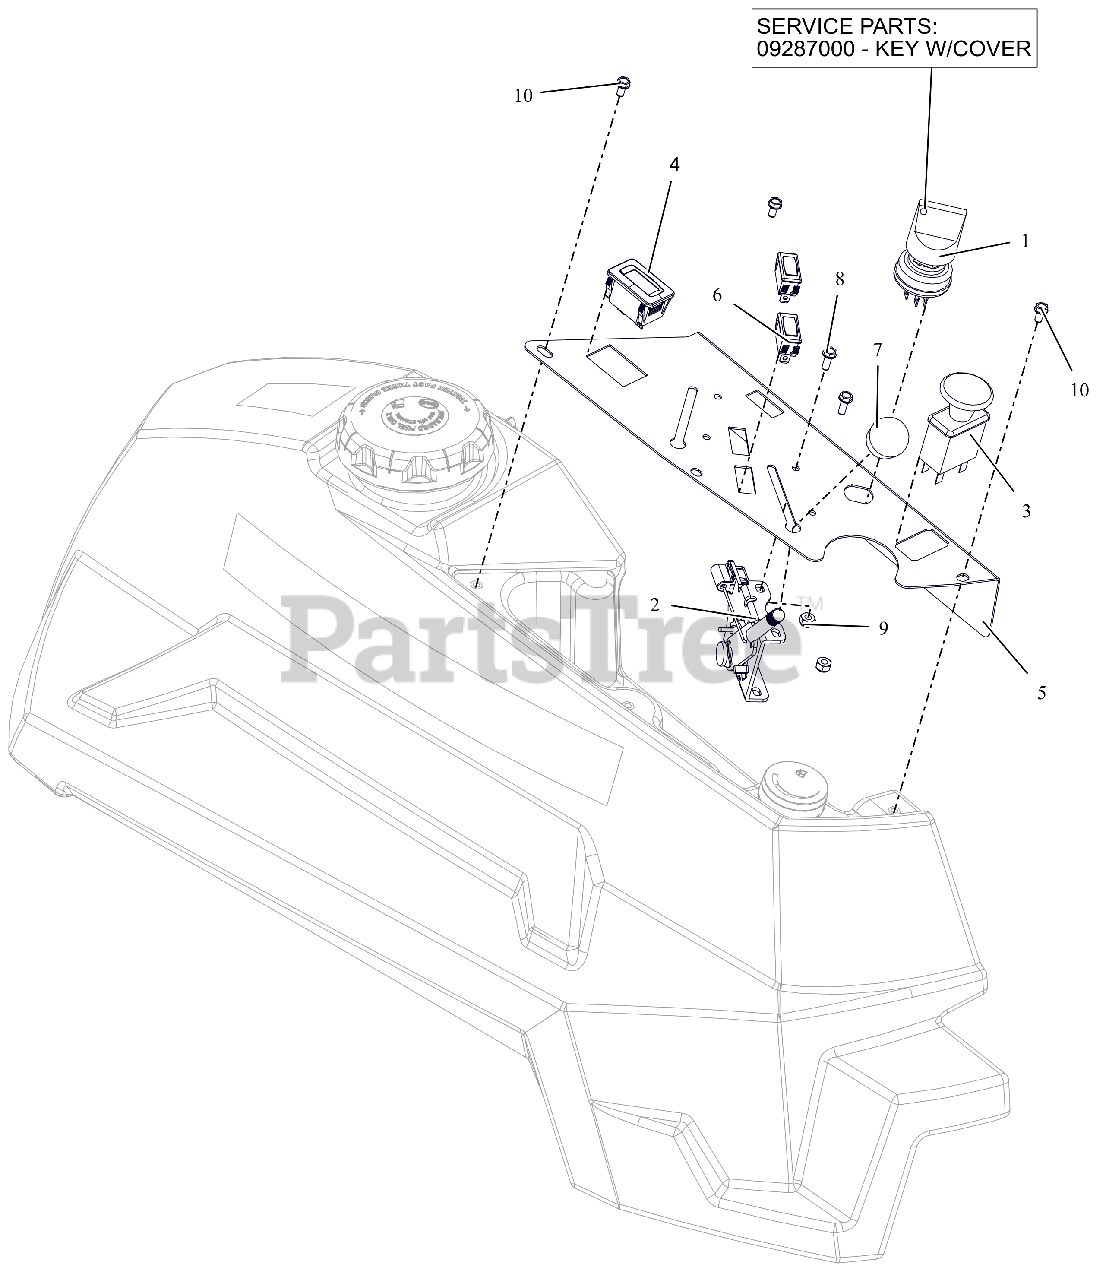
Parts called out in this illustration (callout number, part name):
1	SWITCH, IGNITION
1	KEY, W/ SHIELD
2	CABLE, PRO-CTRL 35.50"
3	SWITCH, CLUTCH
4	HOUR METER
5	PT400 CONTROL PANEL - RED
6	LIGHT, INDICATOR (RED)
7	KNOB-CONTROL-BLACK .38-16X.50
8	BLT, HWH #10-24X.50 ZCC
9	NUT-LK-NYL #10-24 G2 ZCC
10	SCR-MCH 10-24X.38 HWHSTAINLESS
